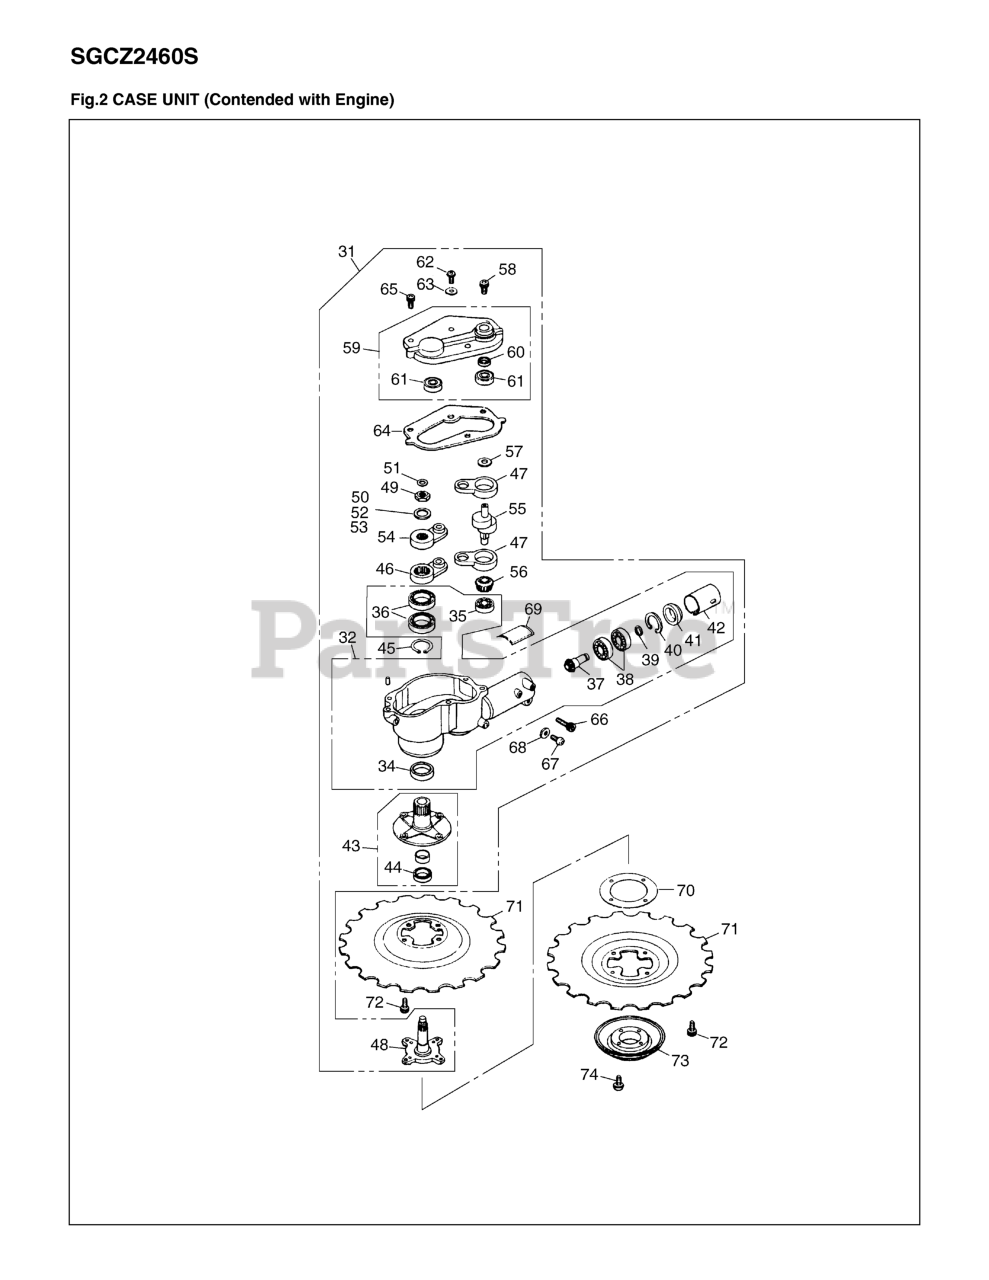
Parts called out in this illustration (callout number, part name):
31	CUTTERCASE ASSEM
32	CUTTERCASE (R-98
34	SEAL, OIL
35	BEARING (RPL 060
37	PINION
38	BEARING (RPLS 06
39	RING, SNAP
40	RING,SNAP M26x1.
41	PACKING
42	SPACER (RPLS 380
43	SHAFT, OUTER-C
44	SEAL, OIL
45	RING, SNAP, M20
46	ARM, LOWER (RPLS
47	CONROD (RPLS 380
48	SHAFT, INNER
49	NUT
50	SHIM, 0.3t
51	SHIM
52	SHIM, 0.2t
53	SHIM, 0.1t
54	ARM, UPPER (RPLS
55	CRANKSHAFT (RPLS
56	GEAR
57	WASHER, M8 x 1.2
58	BOLT
59	COVER COMP
60	SEAL, OIL
61	BEARING (RPL 060
62	SCREW, M6 x 10
63	WASHER, M6 x .8
64	GASKET
65	BOLT, M5 x 20
66	BOLT, M6 x 1.35
67	SCREW, M5 x 14
68	WASHER
69	LABEL, CAUTION
70	SHIM
71	BLADE
72	BOLT, M6 x 8
73	STABILIZER (RPLS
74	SCREW, M5x8 (RPL
